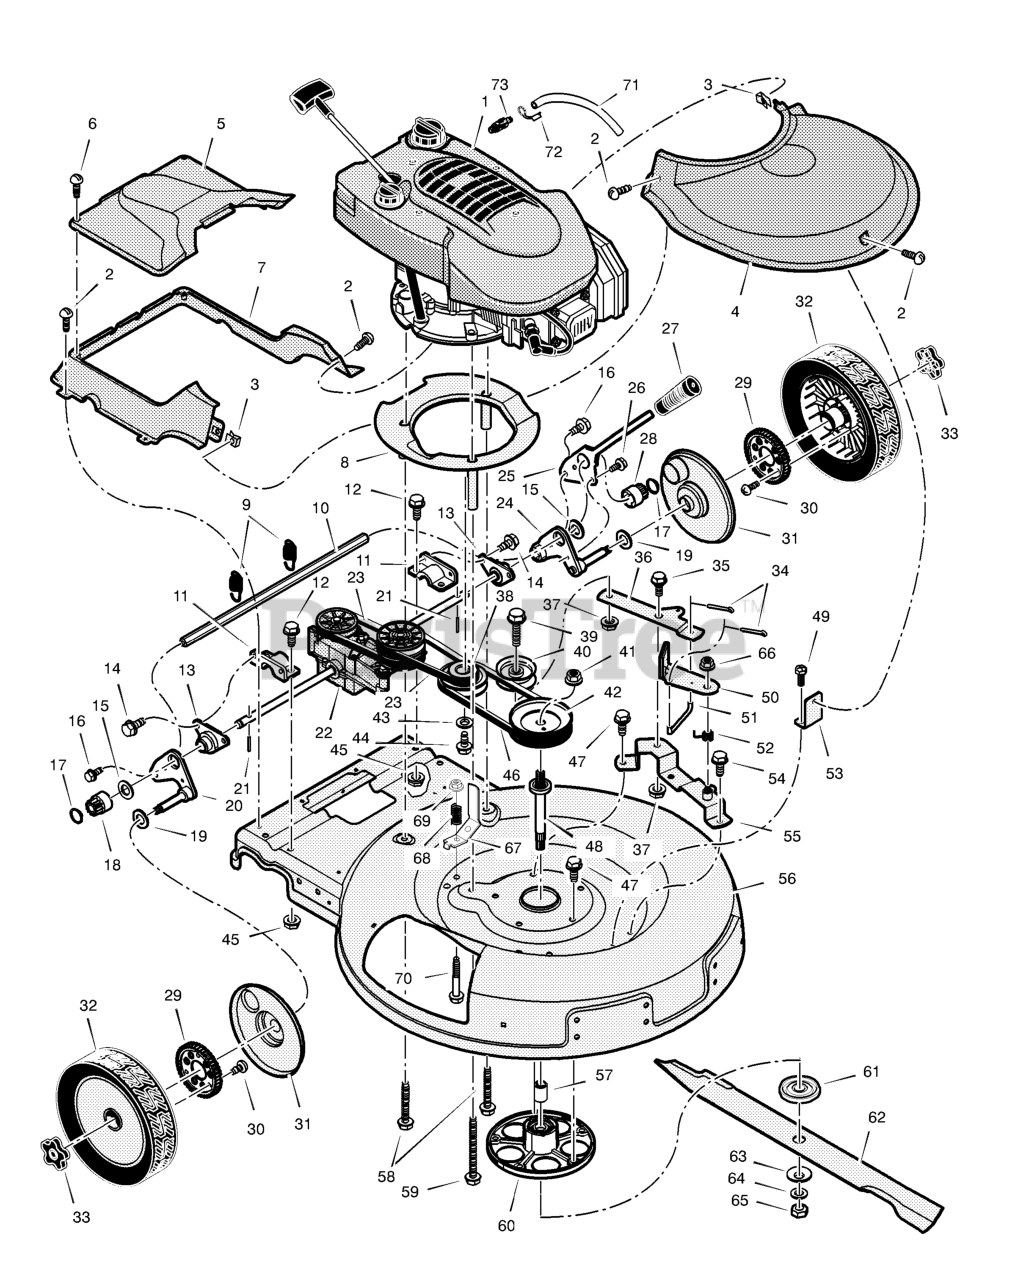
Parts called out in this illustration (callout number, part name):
1	Engine *
3	Tinnerman, "U"
4	Cover, Front
5	Cover, Transmission
7	Cover, Rear
8	Base Assembly, Engine
9	Spring, Extension
10	Crossbar, Rear
11	Bearing, Axle Support
12	Screw
13	Retainer Assembly, Axle Bearing
15	Washer, Thrust
17	Retainer Ring
18	Gear, Right Pinion
19	Washer, Spring
20	Bracket Assembly, Right Axle
21	Pin, Drive
22	Transmission *
23	Belt, Transmission
24	Bracket Assembly, Left Axle
25	Lever, Spring Height Adjuster
26	Screw, Tap
27	Knob, Height Adjuster
28	Gear, Left Pinion
30	Screw, Tap
31	Cover, Dust
32	Wheel, Drive
33	Knob, Axle
34	Pin, Cotter
35	Bolt, Shoulder
36	Idler Arm
37	Nut, Flange
38	Pulley, Engine
39	Screw
40	Pulley, Idler
41	Nut, Blade Pulley
42	Pulley, Blade
43	Washer, Split
44	Screw
46	Belt, Blade Drive
48	Jackshaft
50	Brake Assembly, Blade
51	Link, Blade Brake
52	Spring, Torsion
53	Bracket, Front Cover
55	Support Assembly, Idler & Brake
57	Spacer, Jackshaft
58	Bolt, Short Engine Mount
59	Bolt, Long Engine Mount
60	Mandrel Assembly
61	Adapter, Blade
63	Washer, Cup
64	Washer
65	Nut, Blade Mount
66	Nut
67	Guide, Belt
69	Nut
71	Tube, Oil Drain
72	Cap, Oil Drain
73	Valve, Oil Drain
